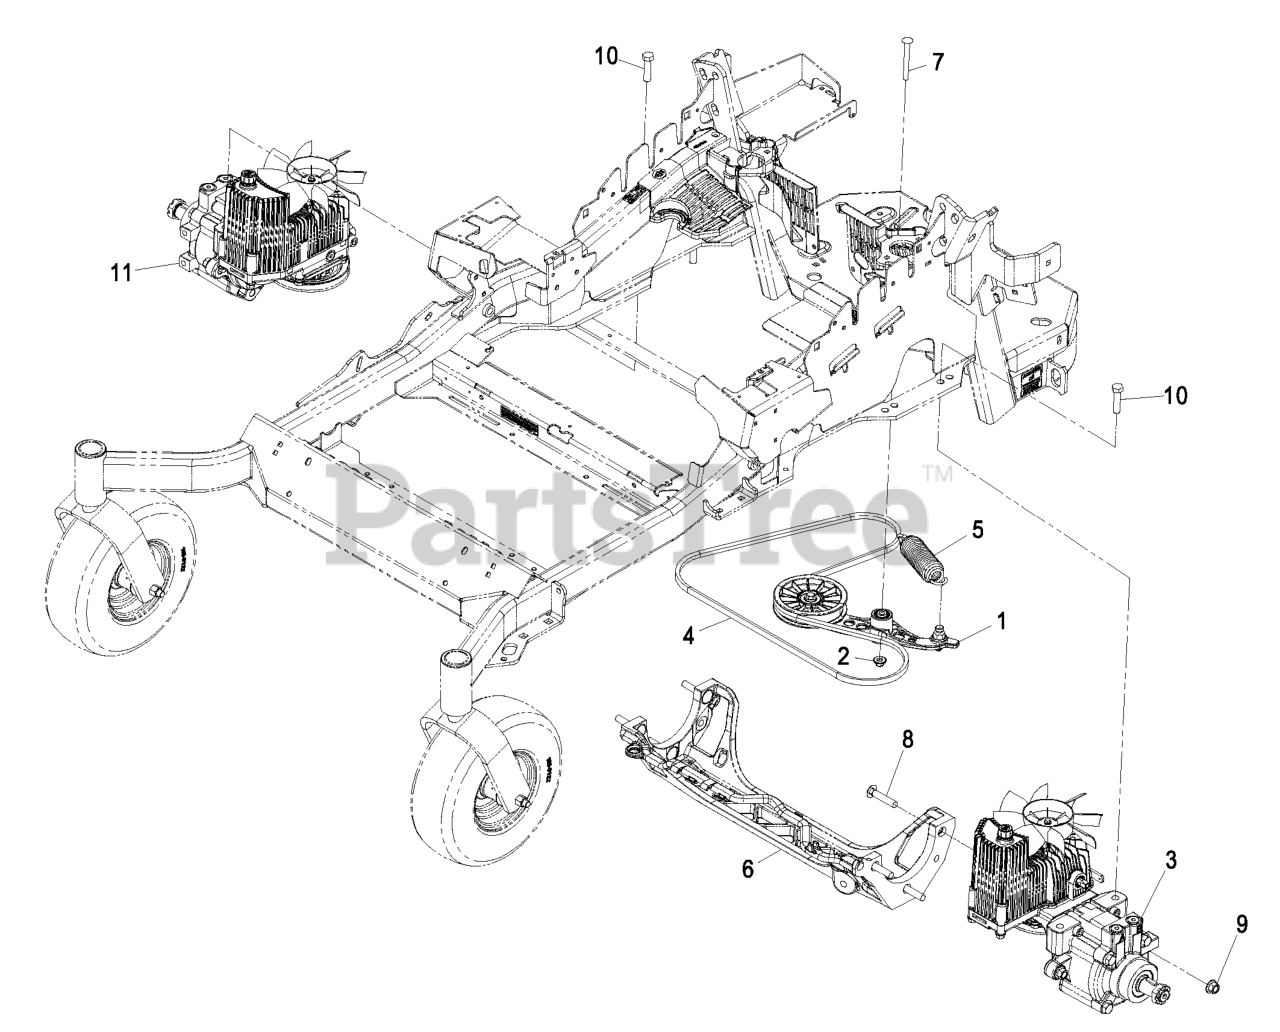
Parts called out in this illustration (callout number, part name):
1	PUMP IDLER ASM
2	Nut-Nyloc 3/8-16 Flg
4	BELT
7	BOLT-SHOULDER, CARRIAGE 3/8-16 X 3 1/2
8	SCREW-CARR
9	Nut-Lock 1/2-13
10	SCREW-HH
